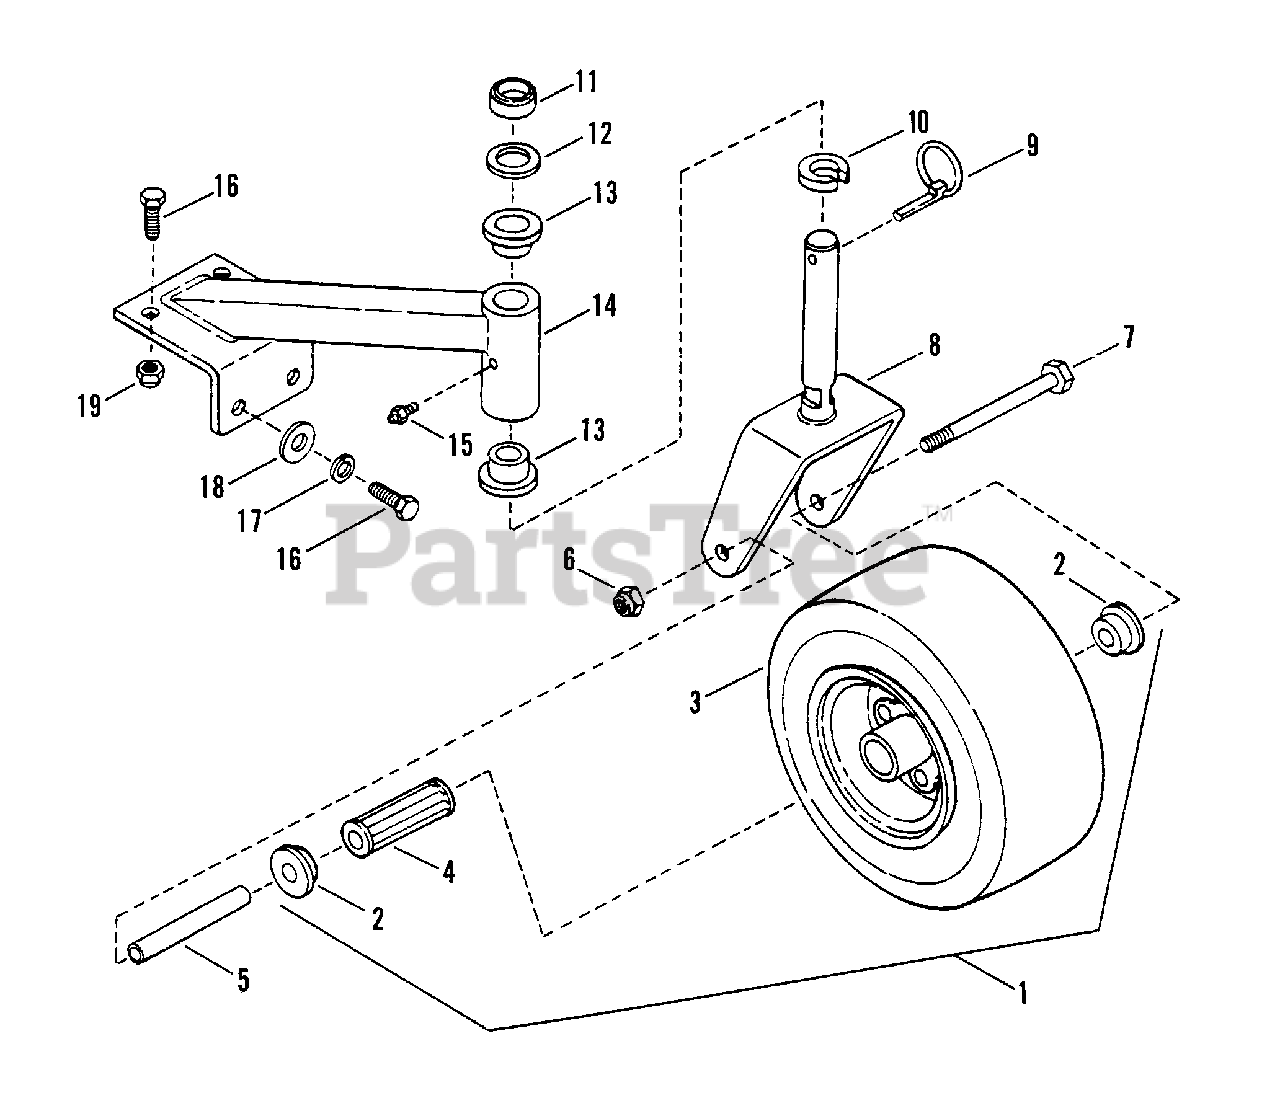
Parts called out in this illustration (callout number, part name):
1	ASSEMBLY, Wheel and Tire
2	RETAINER, Flanged
3	ASSEMBLY, Tire and Rim, 9 x 3.5 Foam-Filled
4	ROLLER BEARING
5	SLEEVE, Axle
6	NUT, 1/2 - 13 Nyloc
7	BOLT, 1/2 - 13 x 5 1/2" HHC
8	YOKE, Caster Weldment
9	PIN, Lynch
10	SPACER
11	SPACER, 1" x 1 3/8 x .30" (PM)
12	SPACER
13	BUSHING, Caster
14	ASSEMBLY, Caster Support
15	FITTING, Lube
16	SCREW, 3/8 - 16 x 1" HHC
17	WASHER, 3/8 Lock
18	WASHER, 3/8" Flat
19	NUT, 3/8 - 16 Nyloc
